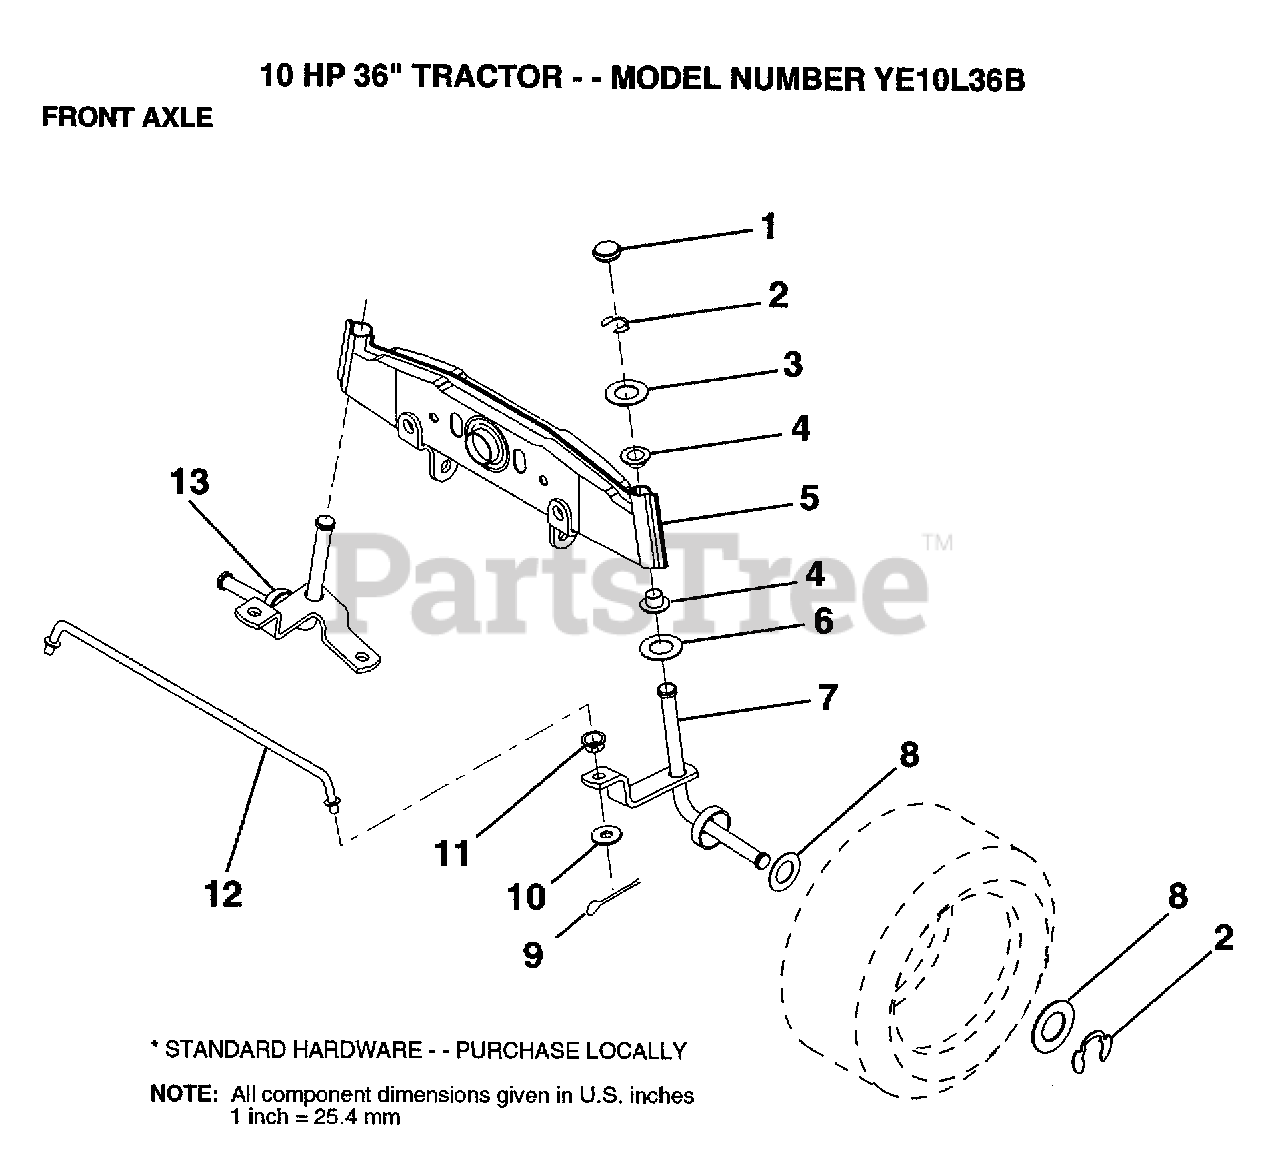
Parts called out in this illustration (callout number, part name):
1	CAP
2	RING
3	WASHER
4	NYLINER
5	AXLE FRONT
6	WASHER .T
7	SPINDLE RH
8	WASHER
9	COTTER PIN
10	WASHER
11	BUSHING.DRAGLINK
12	ROD TIE
13	SPINDLE LH
